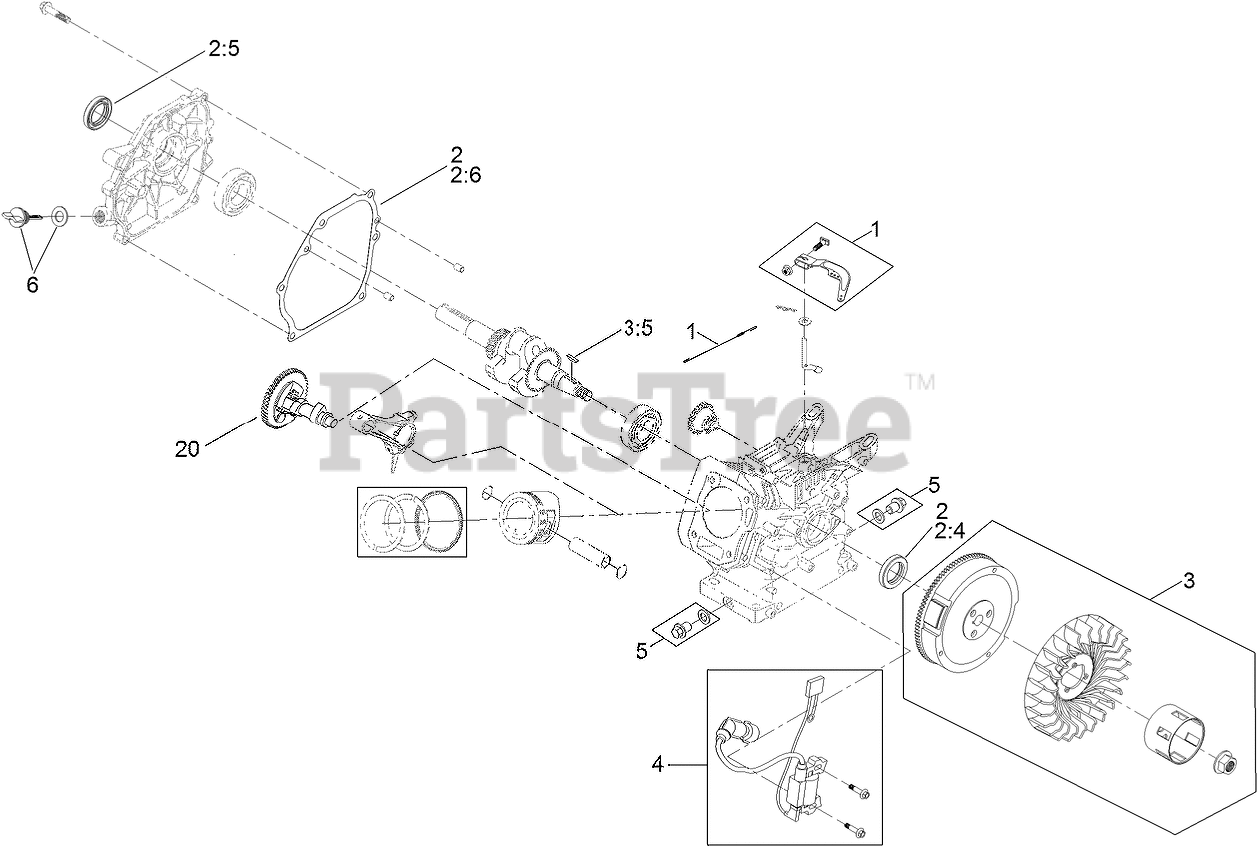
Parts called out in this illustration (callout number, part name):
1	GOVERNOR KIT
2	GASKET AND SEAL KIT
2:5	SEAL-OIL
2:6	GASKET-COVER, CRANKCASE
3	FLYWHEEL KIT
3:5	KEY-WOODRUFF
4	IGNITION KIT
5	DRAIN PLUG KIT
6	DIPSTICK AND O-RING KIT
20	CAMSHAFT
